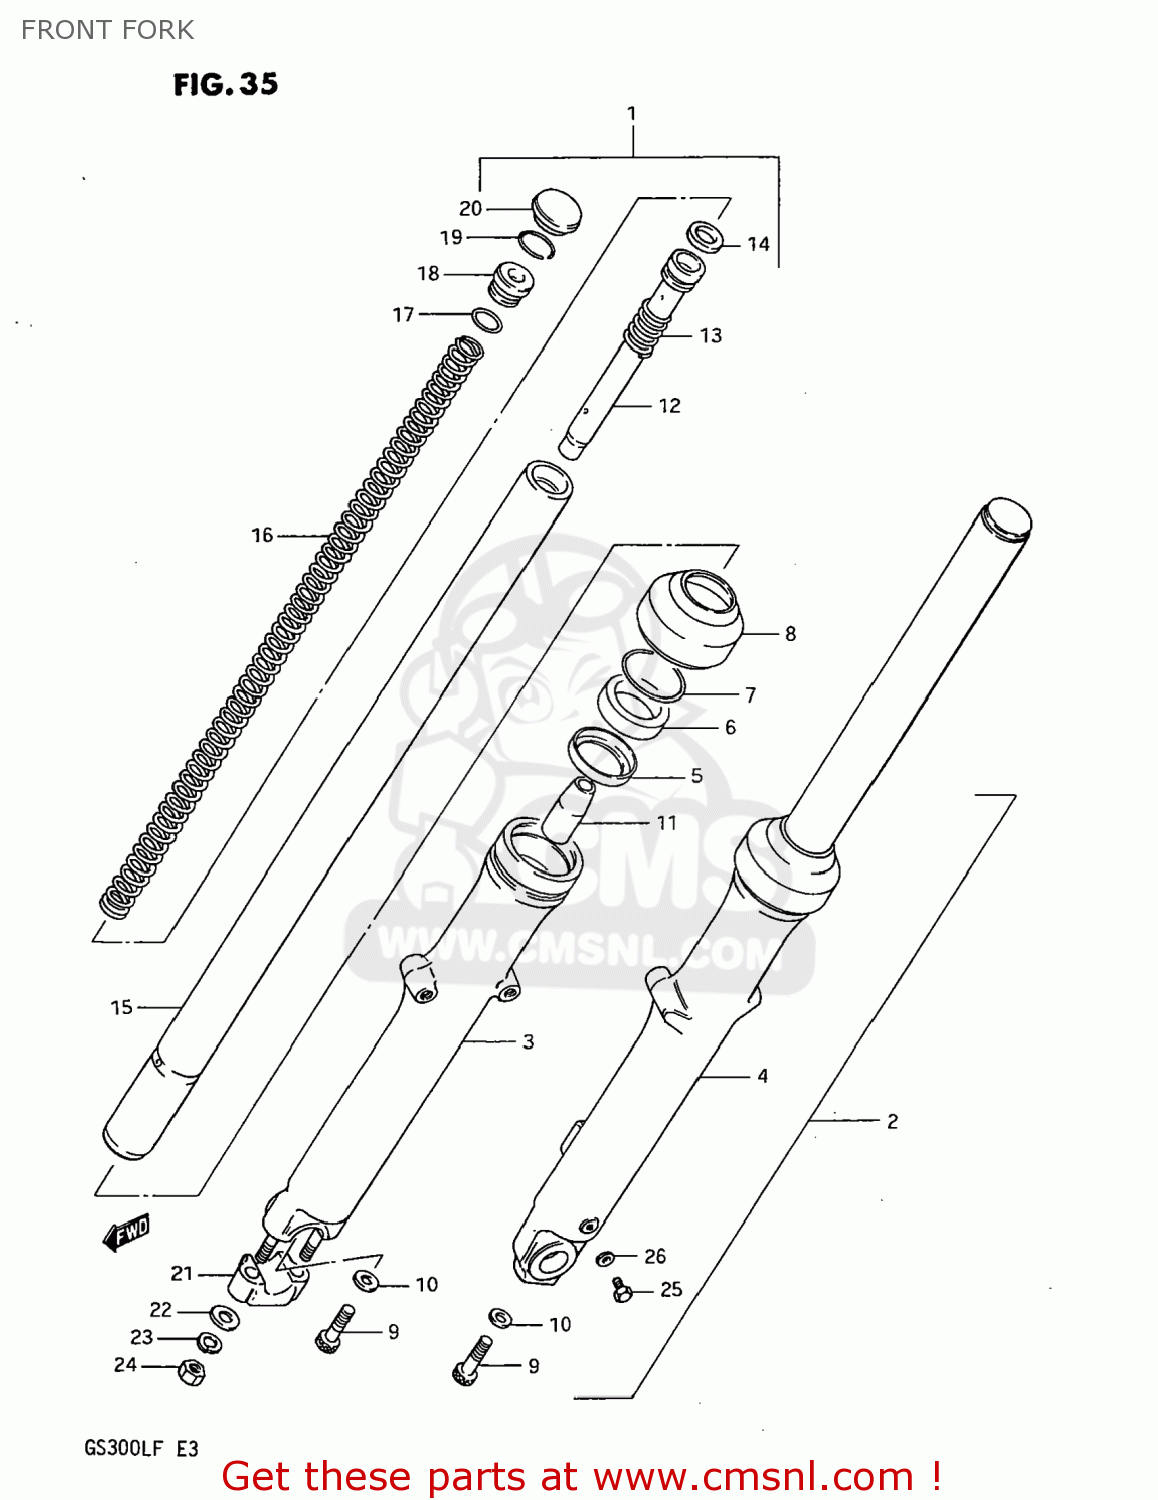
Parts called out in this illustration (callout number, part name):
1	DAMPER ASSEMBLY,FRONT FORK
2	DAMPER ASSEMBLY,FRONT FORK,LEFT
3	TUBE,OUTER,RIGHT
4	TUBE,OUTER,LEFT
5	SPACER,OIL SEAL
6	OIL SEAL,FRONT FORK
7	CIRCLIP,FORK OIL SEAL
8	DUST SEAL
9	BOLT(8X27)
10	GASKET (NAS)
11	PIECE,OIL LOCK
12	CYLINDER,FRONT FORK
13	SPRING,REBOUND
14	RING,PISTON
15	TUBE,FORK,INNER
16	SPRING,FRONT FORK
17	O RING
18	SEAT,SPRING
19	RING,STOPPER
20	CAP,FRONT FORK
21	HOLDER,AXLE
22	WASHER
23	LOCK WASHER
24	NUT
25	BOLT(6X8)
26	GASKET,DRAIN,PLUG (NAS)
